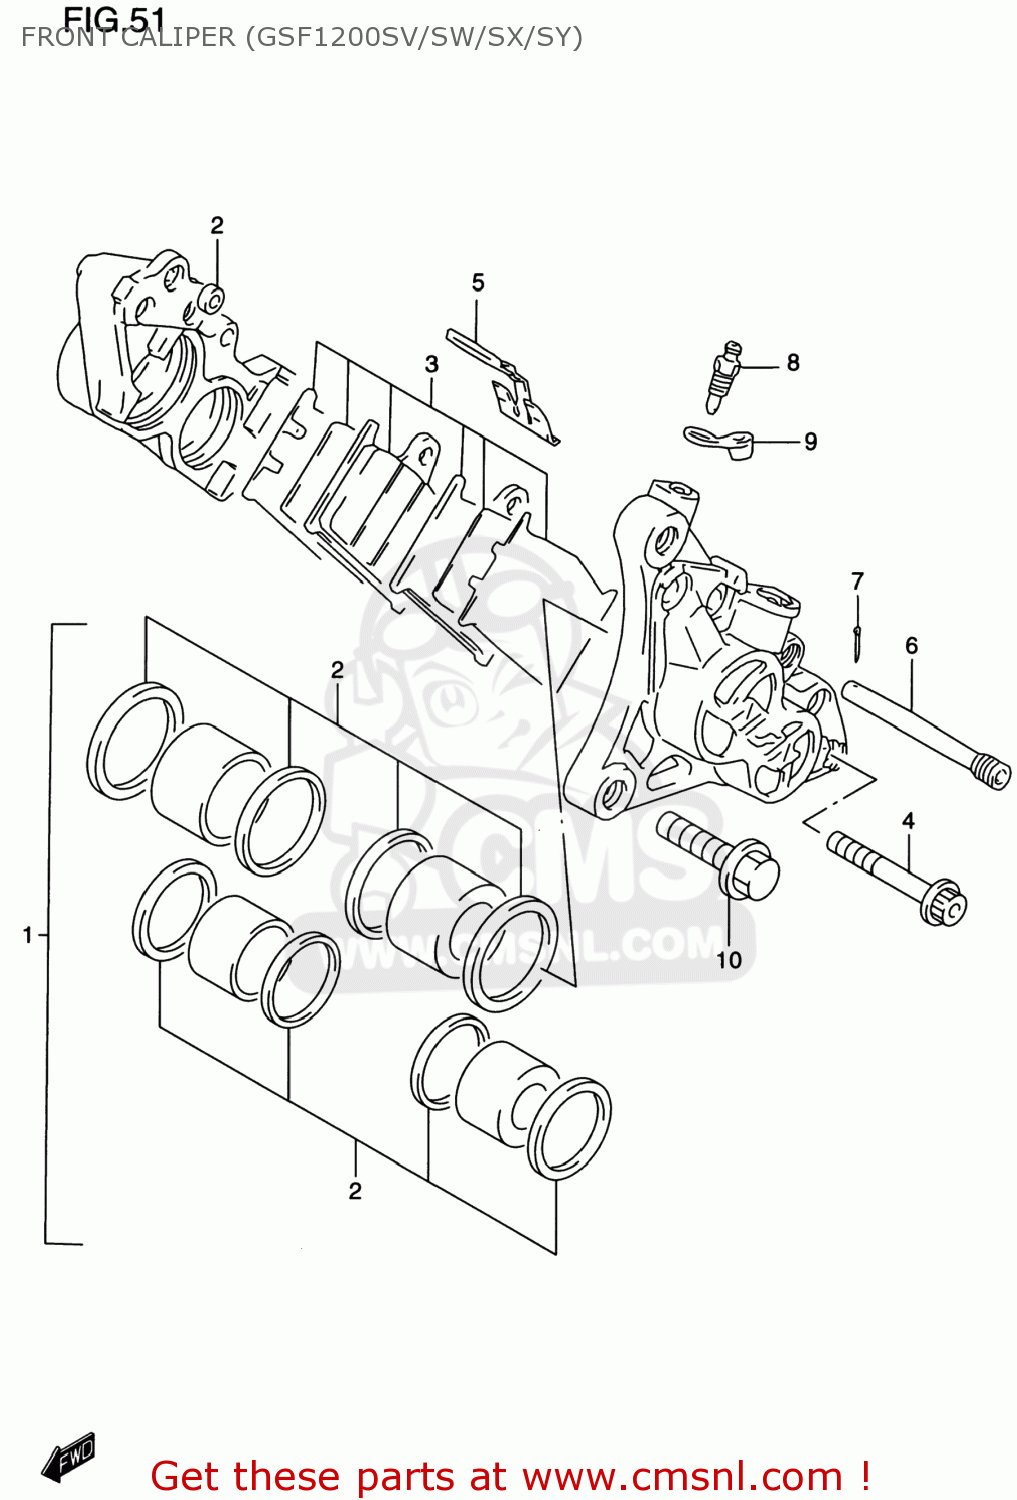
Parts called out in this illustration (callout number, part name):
1	PISTON SET
2	SEAL SET,PISTON
3	PAD & SHIM SET (NAS)
4	BOLT
5	SPRING
6	PIN,HANGER
7	PIN 16X20
8	BLEEDER
9	CAP,BLEEDER
10	BOLT
